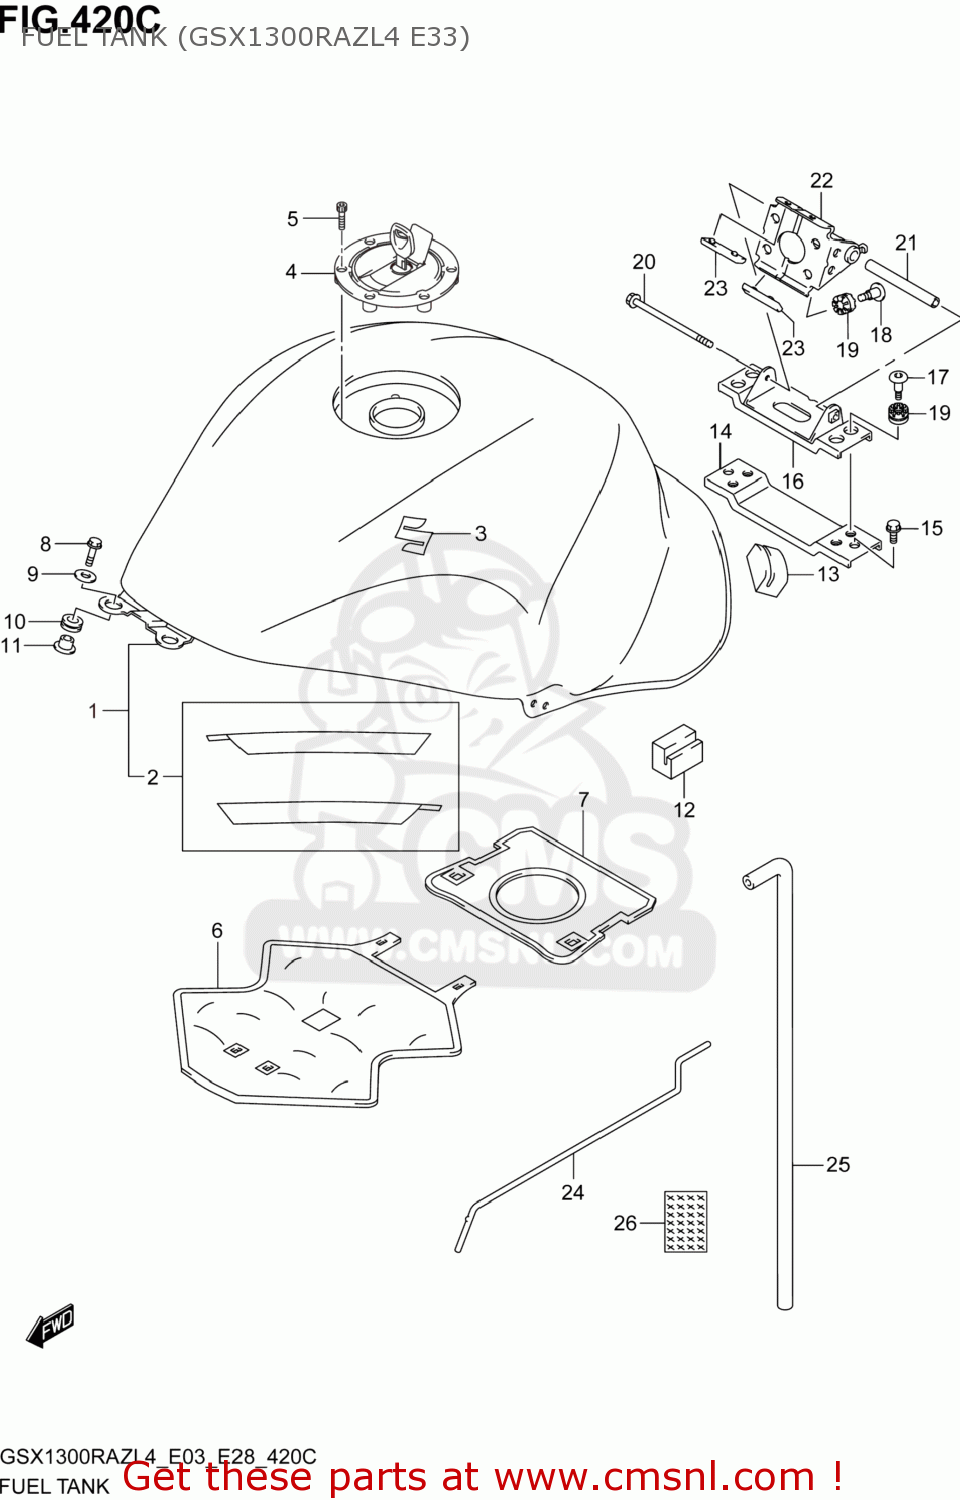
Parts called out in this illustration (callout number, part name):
1	TANK ASSY,FUEL
2	TAPE SET,FUEL TANK LOWER
3	EMBLEM, S
4	CAP SET,FUEL TANK
5	BOLT(5X20)
6	SHIELD,FUEL TANK HEAT NO.1
7	SHIELD,FUEL TANK HEAT NO.2
8	SCREW(6X25)
9	WASHER(6,5X22X1.6)
10	CUSHION,FUEL TANK FR
11	SPACER,FUEL TANK FR
12	CUSHION,FUEL TANK SIDE
13	CUSHION,FUEL TANK RR
14	BRACKET,FUEL TANK RR NO.3
15	BOLT
16	BRACKET,FUEL TANK RR NO.2
17	SCREW(6X22)
18	SCREW(6X22)
19	CUSHION
20	BOLT
21	SPACER,FUEL TANK RR
22	BRACKET,FUEL TANK RR NO.1
23	CUSHION,SEAT FR
24	STAY,FUEL TANK
25	HOSE,FUEL TANK DRAIN
26	SHIELD,DRAIN HOSE HEAT
